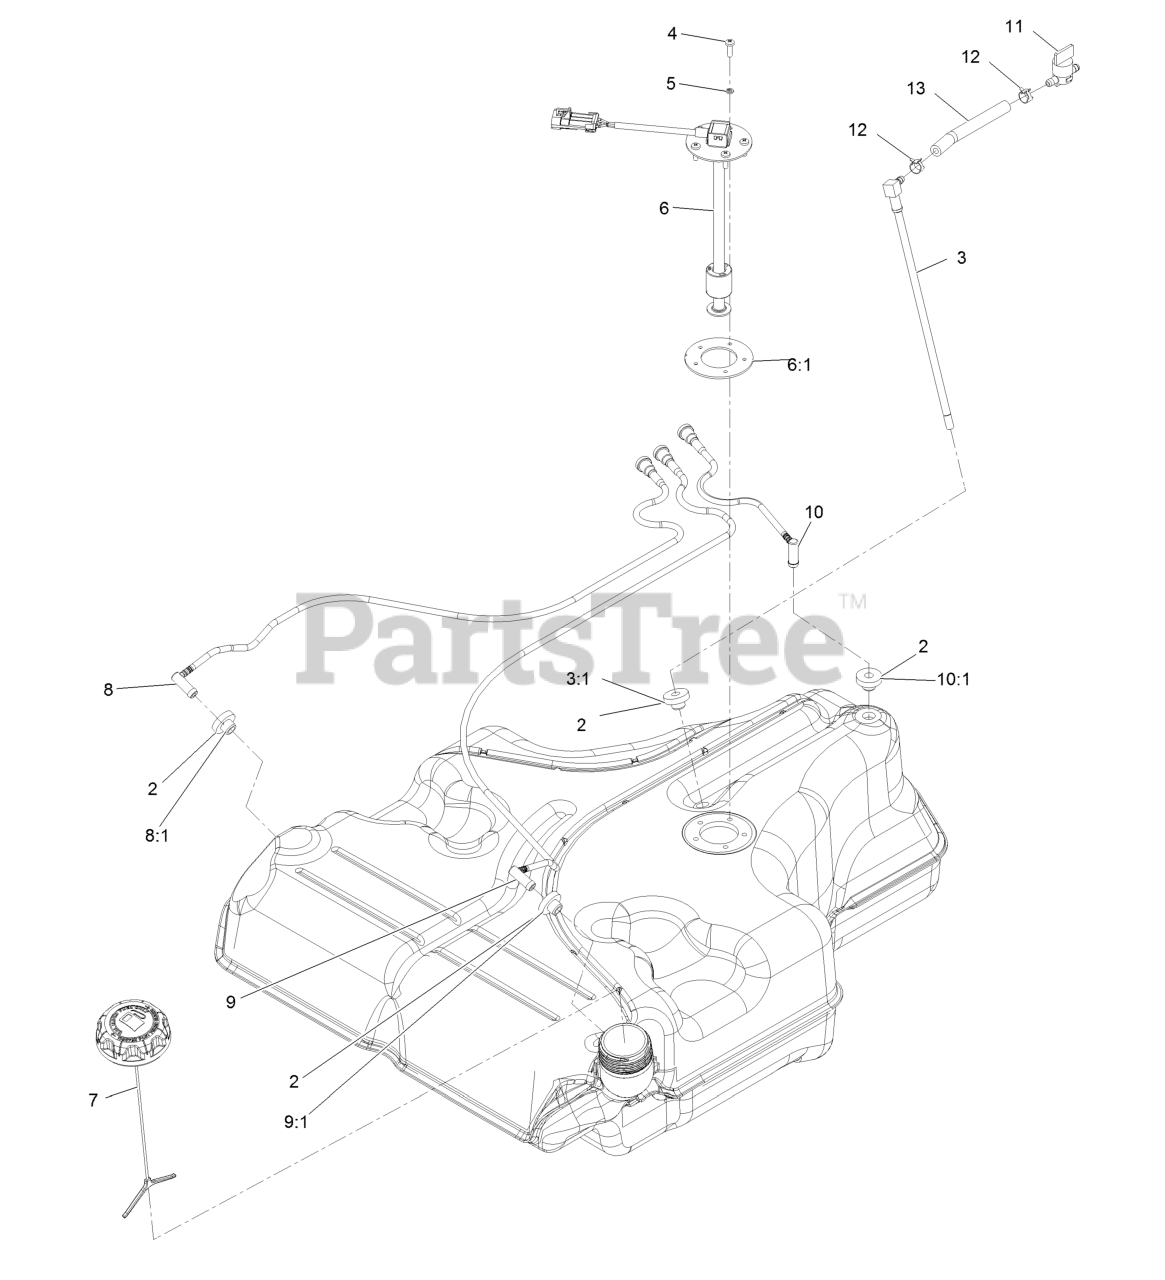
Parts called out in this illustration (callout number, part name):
2	BUSHING
3	FUEL LINE KIT (WITH GROMMET)
3:1	BUSHING
4	SCREW-PPH
5	WASHER-LOCK
6	FLOAT-SENDER, FUEL
6:1	Gasket-Sender
7	CAP-FUEL, RATCHETING
8	RH VENT LINE KIT (WITH GROMMET)
8:1	BUSHING
9	LH VENT LINE KIT (WITH GROMMET)
9:1	BUSHING
10	REAR VENT LINE KIT (WITH GROMMET)
10:1	BUSHING
11	VALVE-FUEL
12	CLAMP-HOSE
13	HOSE-FUEL
